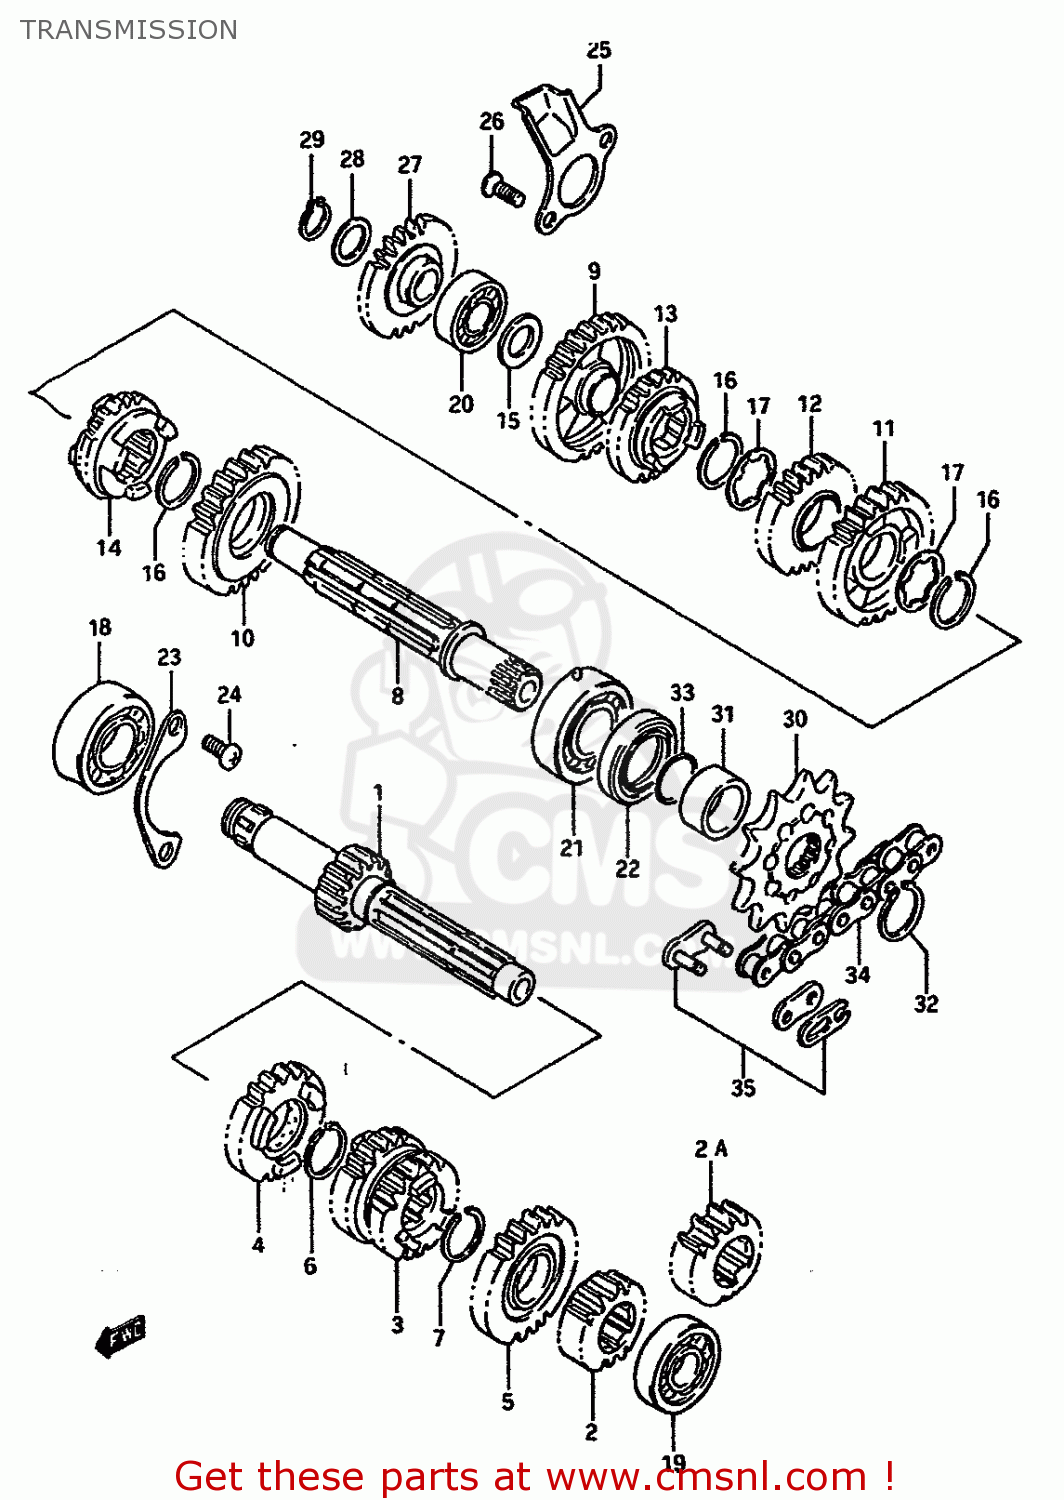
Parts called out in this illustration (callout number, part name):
1	SHAFT,COUNTER
2	GEAR,SECOND DRIVE (NT:13)
2A	GEAR,SECOND DRIVE
3	GEAR,THIRD & FOURTH DRIVE
4	GEAR,FIFTH DRIVE (NT:19)
5	GEAR,SIXTH DRIVE (NT:20)
6	CIRCLIP
7	CIRCLIP
8	SHAFT,DRIVE
9	GEAR,FIRST DRIVEN
10	GEAR,SECOND DRIVEN
11	GEAR,THIRD DRIVEN
12	GEAR,FOURTH DRIVEN
13	GEAR,FIFTH DRIVEN
14	GEAR,SIXTH DRIVEN
15	WASHER,THRUST
16	CIRCLIP
17	WASHER,LOCK
18	BEARING
19	BEARING
20	BEARING
21	BEARING(20X47X14)
22	SEAL,OIL(25X40X7)
23	RETAINER,CENTER SHAFT BEARING
24	SCREW 6X12
25	PLATE,DRIVESHAFT BEARING
26	SCREW
27	GEAR,KICK STARTER IDLE
28	WASHER,THRUST
29	CIRCLIP,15MM
30	SPROCKET,ENGINE
31	SPACER(20X25X12.8)
32	CIRCLIP
33	O RING(D:1,ID:19.5)
34	CHAIN ASSEMBLY,DRIVE
35	JOINT ASSEMBLY,CHAIN
